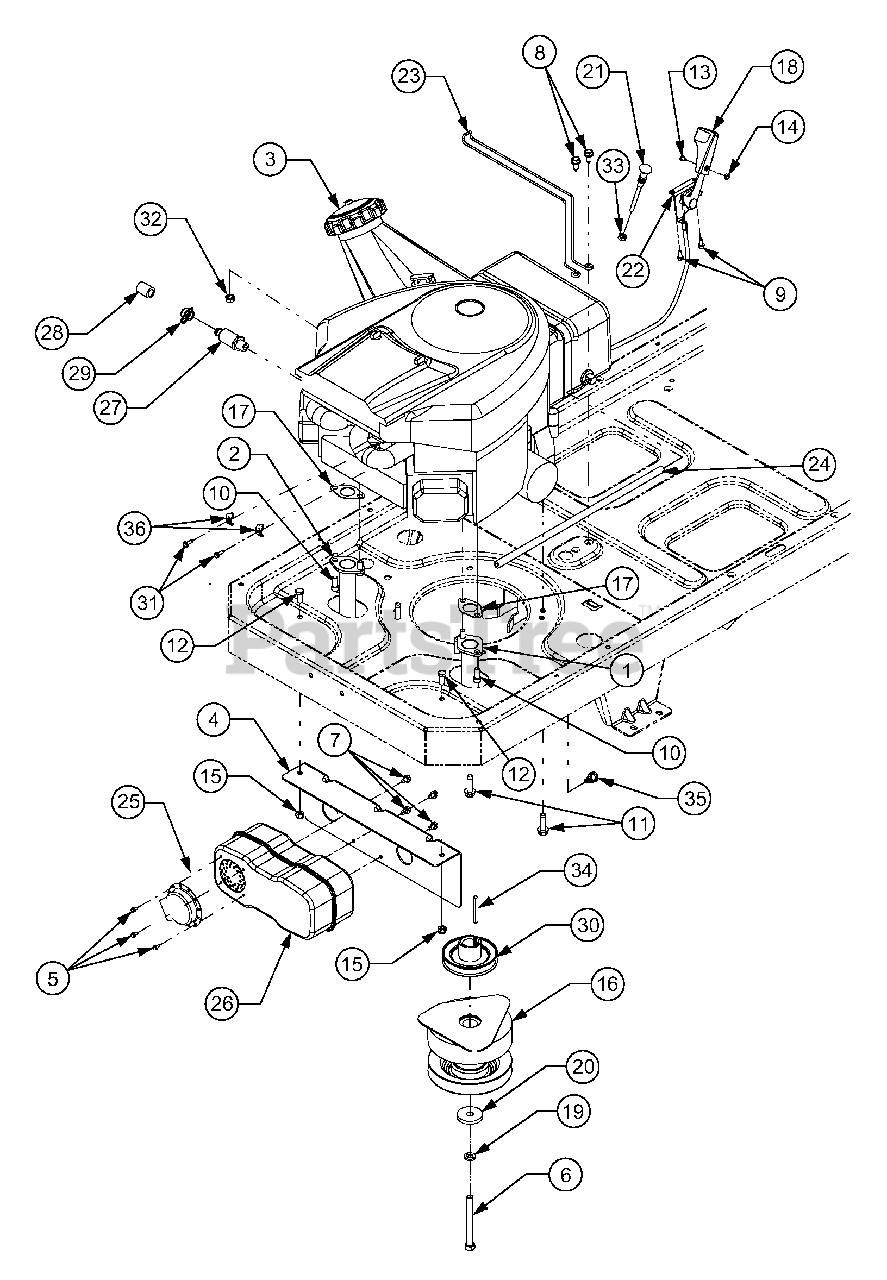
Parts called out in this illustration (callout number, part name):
1	Tube, Exhaust RH
2	Tube, Exhaust LH
3	Tank, Fuel, 3.0 Gal.
4	Bracket, Muffler Mounting
5	Screw, Hex Wash. Hd. Tapp #8-18 x .5
6	Screw, Hex Cap, 7/16-20 x 4.0 GR5
7	Screw, Hex Wash. Hd. Tapp 1/4-20 x .5
8	Screw, Hex Wash. Hd. Tapp 5/16-12 x .75
9	Screw, Hex Wash. Hd. Tapp #12-16 x .5
10	Screw, Socket Hd. 5/16-18 x .75
11	Screw, Hex Wash. Hd. Tapp 3/8-16 x 1.25
12	Screw, Hex Cap, 5/16-18 x .75 GR5
13	Screw, Truss Hd. Mach. #8-32 x .375
14	Nut, Hex, #8-32
15	Nut, Hex Insert Lock, 5/16-18 GR5
16	Clutch Assembly, Electric PTO
17	Gasket, Exhaust
18	Knob, Throttle Control
19	Washer, Lock, 7/16
20	Washer, Flat, .438 x 1.75 x .25
21	Cable, Choke, 61Lg
22	Cable, Throttle, 39.0 Lg
23	Wire, Tank Mounting
24	Hose, Fuel Line
25	Deflector, Muffler
26	Muffler
27	Valve, Oil Drain
28	Hose, Oil Drain Extension
29	Cap, Oil Drain Valve
30	Pulley, Drive, 3.25 Dia.
31	Screw, Hex Wash. Hd. Tapp #10-32 x 0.625
32	Nut, Hex Sems, 1/4-20
33	Nut, Hex Jam, 3/8-24 GR2
34	Key, Square, 1/4 x 2.25
35	Clip, Cable Retainer
36	Clamp, Casing
